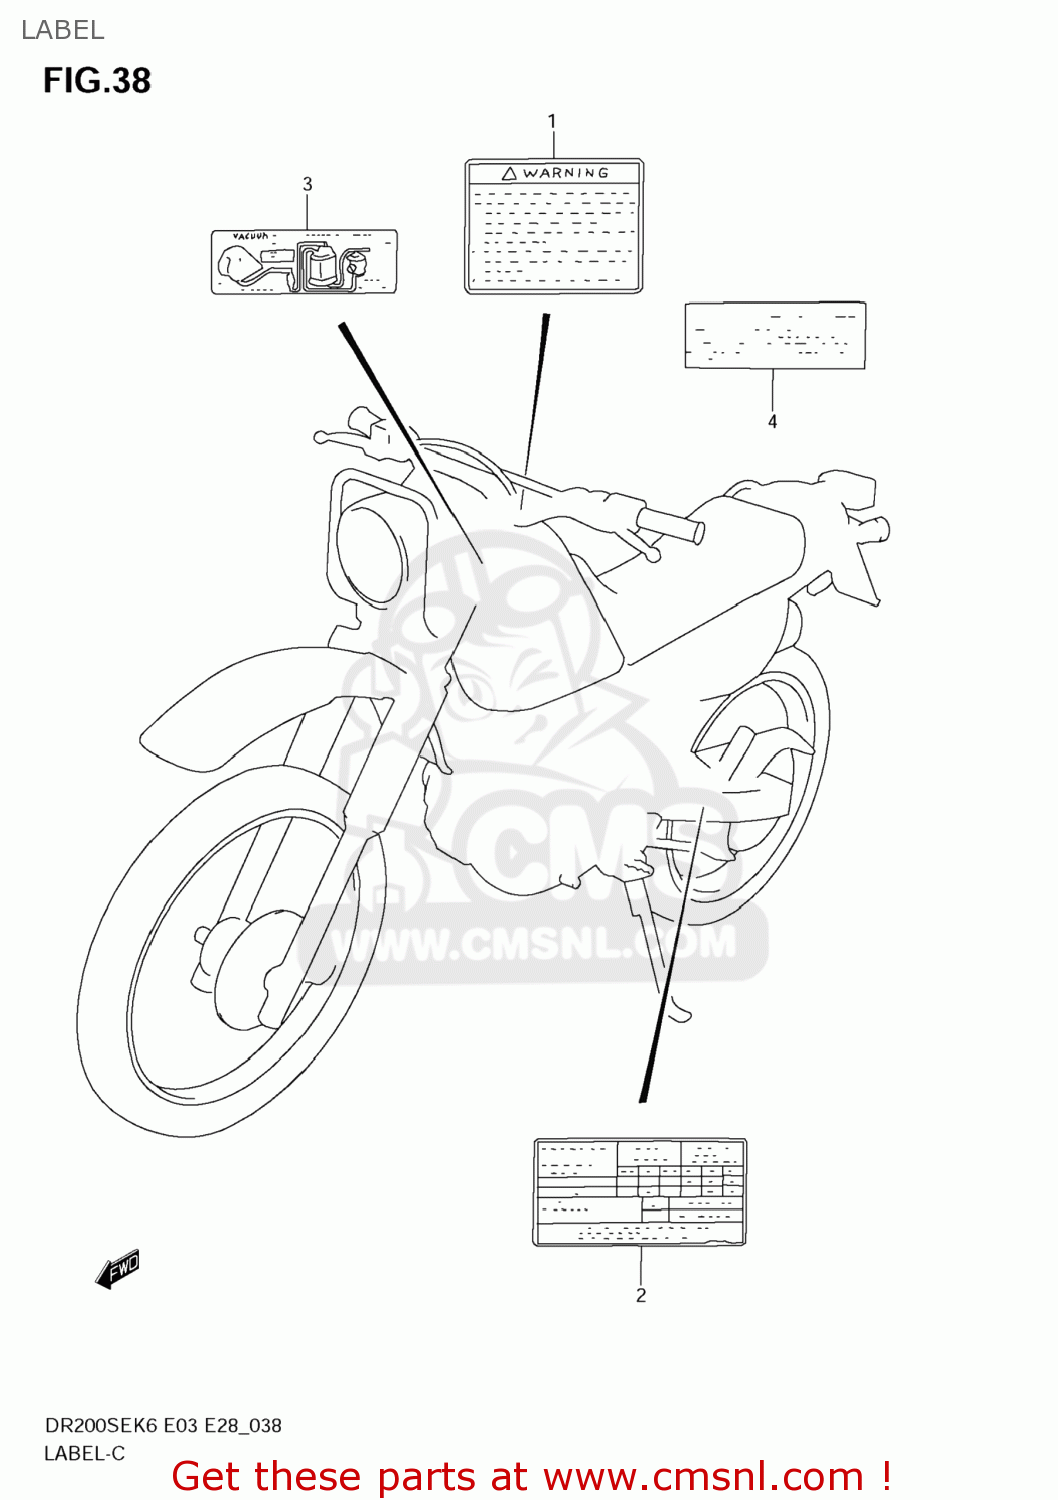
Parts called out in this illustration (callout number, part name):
1	LABEL,GENERAL WARNING
2	LABEL,TIRE INFORMATION
3	LABEL,PIPING DIAG
4	LABEL,MANUAL NOTICE
5	MANUAL,OWNER'S
